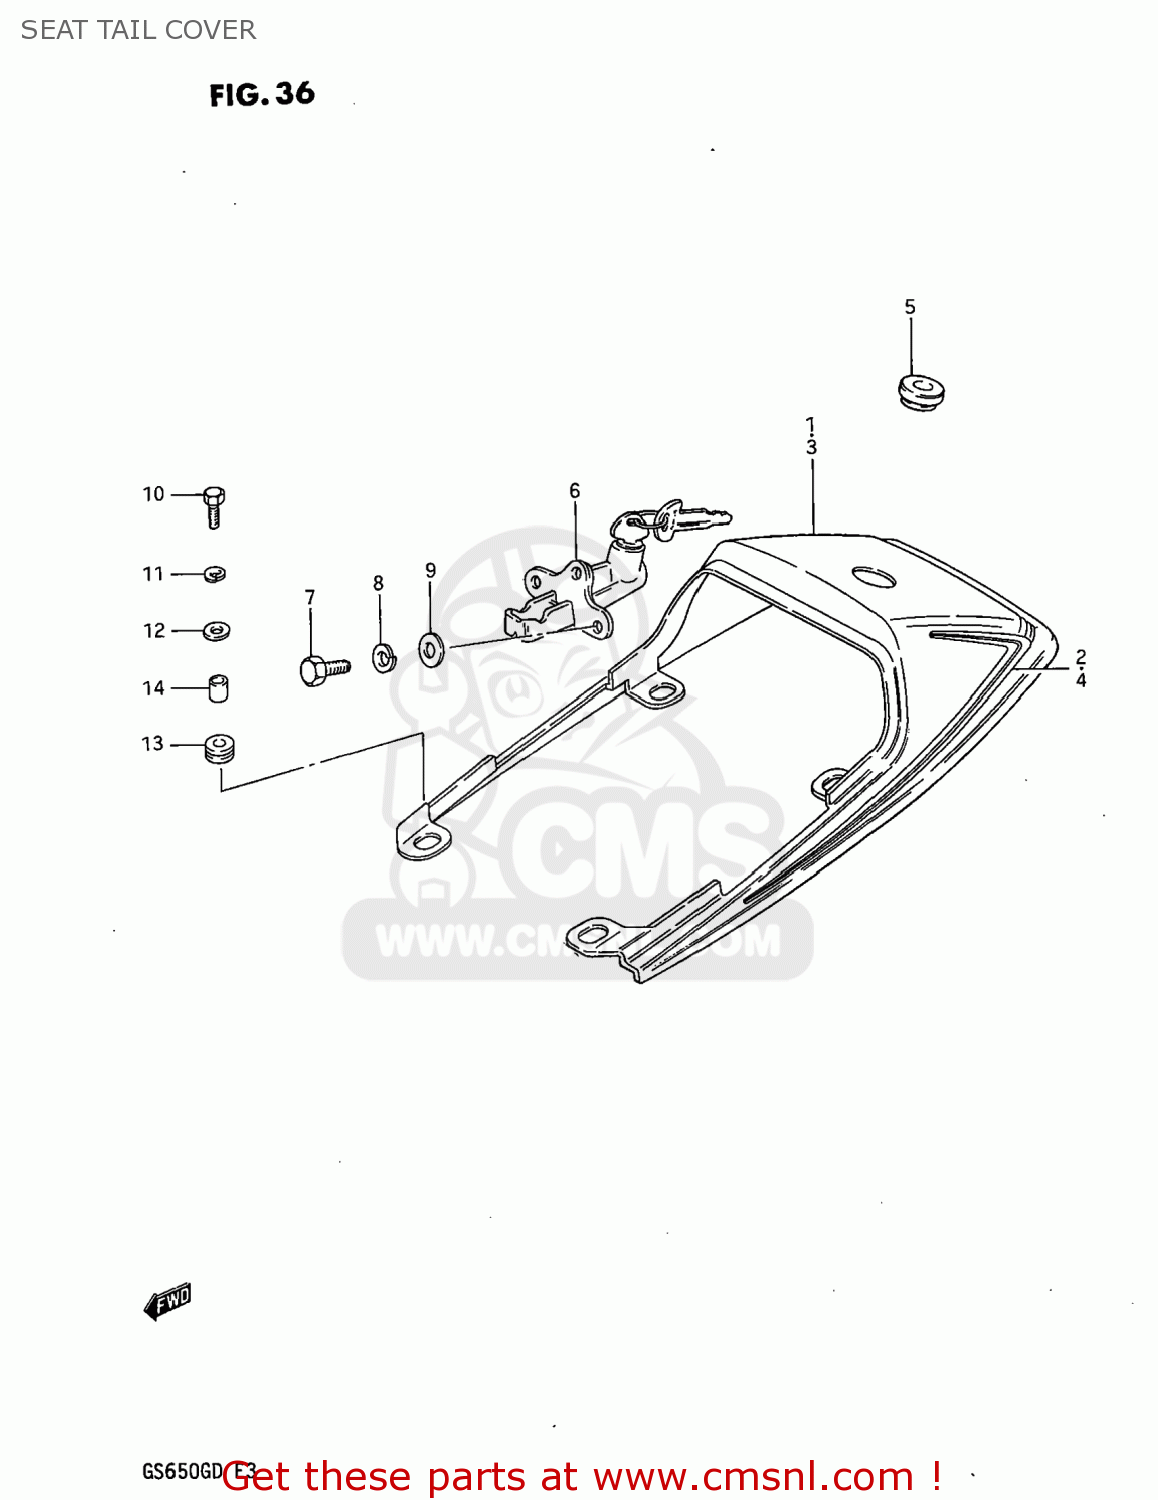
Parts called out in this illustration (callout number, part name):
1	BOX ASSEMBLY,SEAT TAIL
2	TAPE SET,BOX SEAT TAIL
3	BOX ASSEMBLY,SEAT TAIL
4	TAPE SET,BOX SEAT TAIL
5	GROMMET,SEAT LOCK HOLE
6	LOCK SET,SEAT
7	BOLT
8	LOCK WASHER
9	WASHER
10	BOLT
11	LOCK WASHER
12	WASHER(6,5X22X1.6)
13	CUSHION
14	SPACER(6.5X10.5X12)
